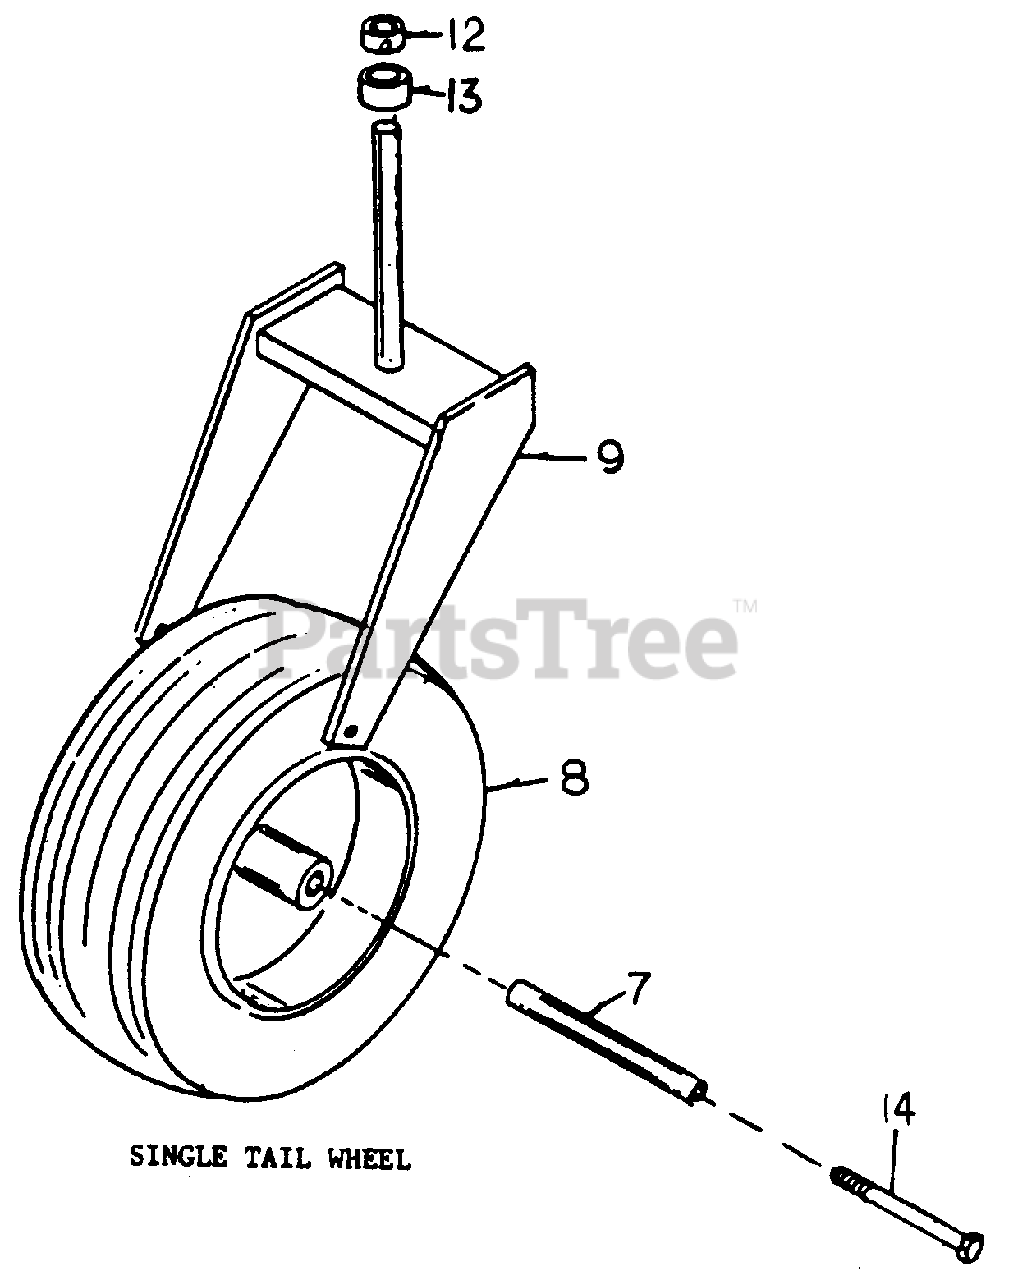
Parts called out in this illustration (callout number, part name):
7	Axle
8	Tail Wheel Assembly
9	Tail Wheel Fork
12	Set Collar, 1"
13	Spacer, Tail Wheel Fork
14	Hex Capscrew, 1/2-13 x 8 1/2"
